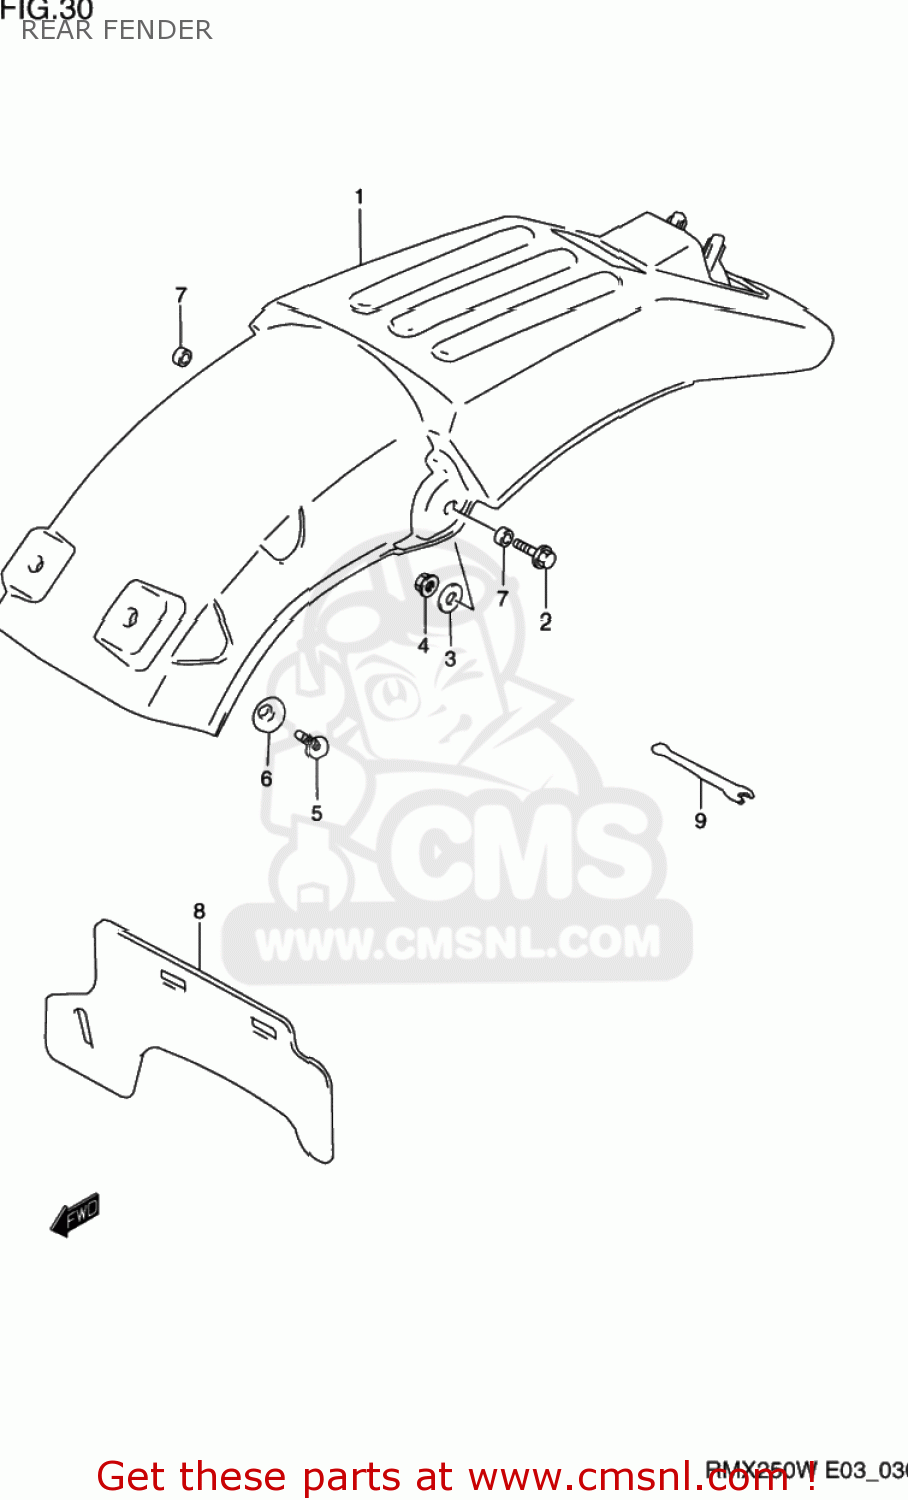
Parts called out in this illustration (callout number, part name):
1	BODY,RR FENDER
2	BOLT
3	WASHER(8.5X20X1.6)
4	NUT
5	SCREW
6	WASHER
7	SPACER(8.5X12X4)
8	MUDGUARD,RR FENDER
9	SPANNER,OPEN
